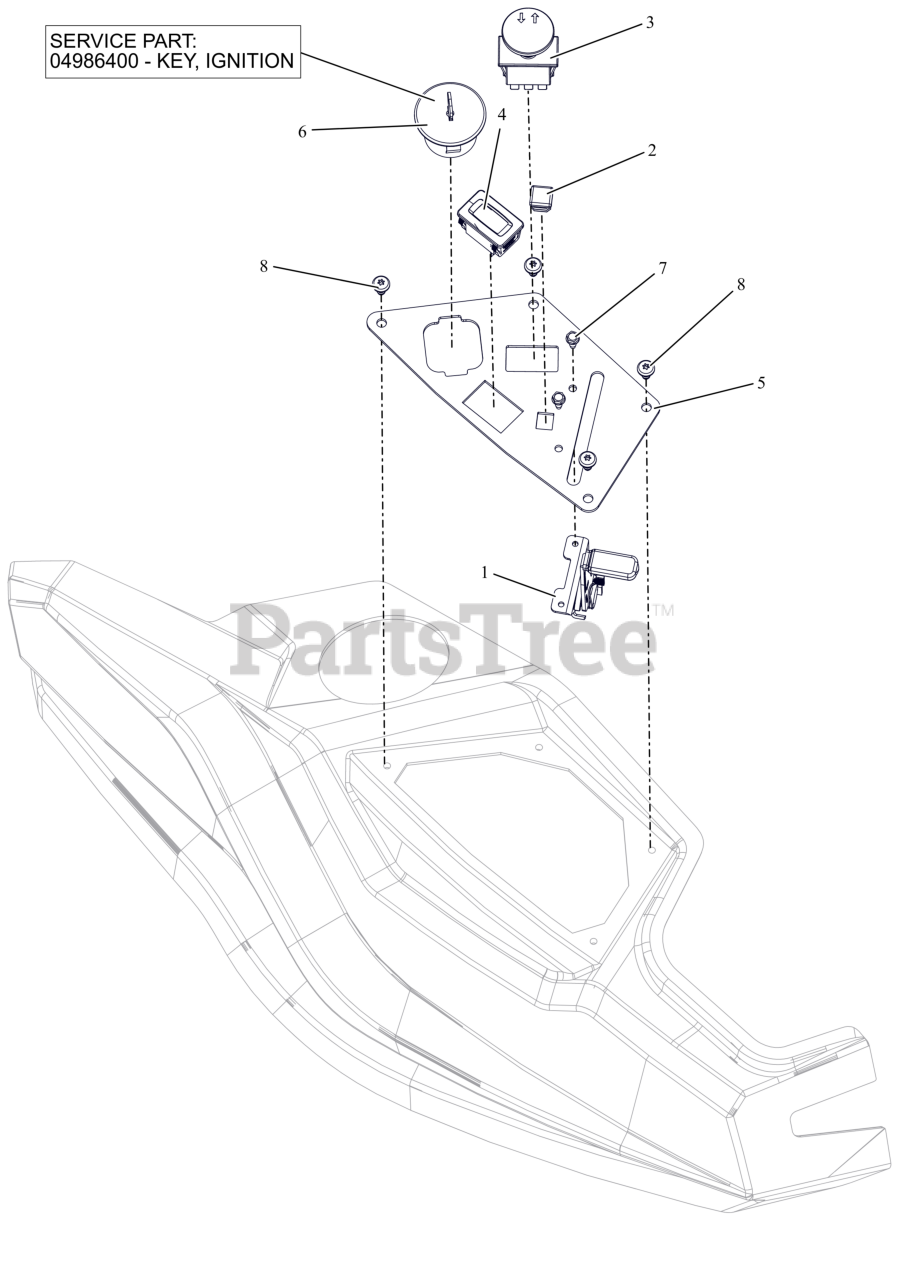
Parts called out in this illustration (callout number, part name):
1	CABLE, THROTTLE
2	PLUG, 5/8" SQ BLACK (14-20GA)
3	SWITCH, CLUTCH (YELLOW)
4	HOUR METER
5	PANEL, CONTROL (ORANGE)
6	KEYSWITCH-IGNITION 3 POS
6	KEY, IGNITION
7	SCR,TAP #10-24X.50 HWH TR ZCC
8	SCR-PAN .25-15X.50 6L H/LZB500
